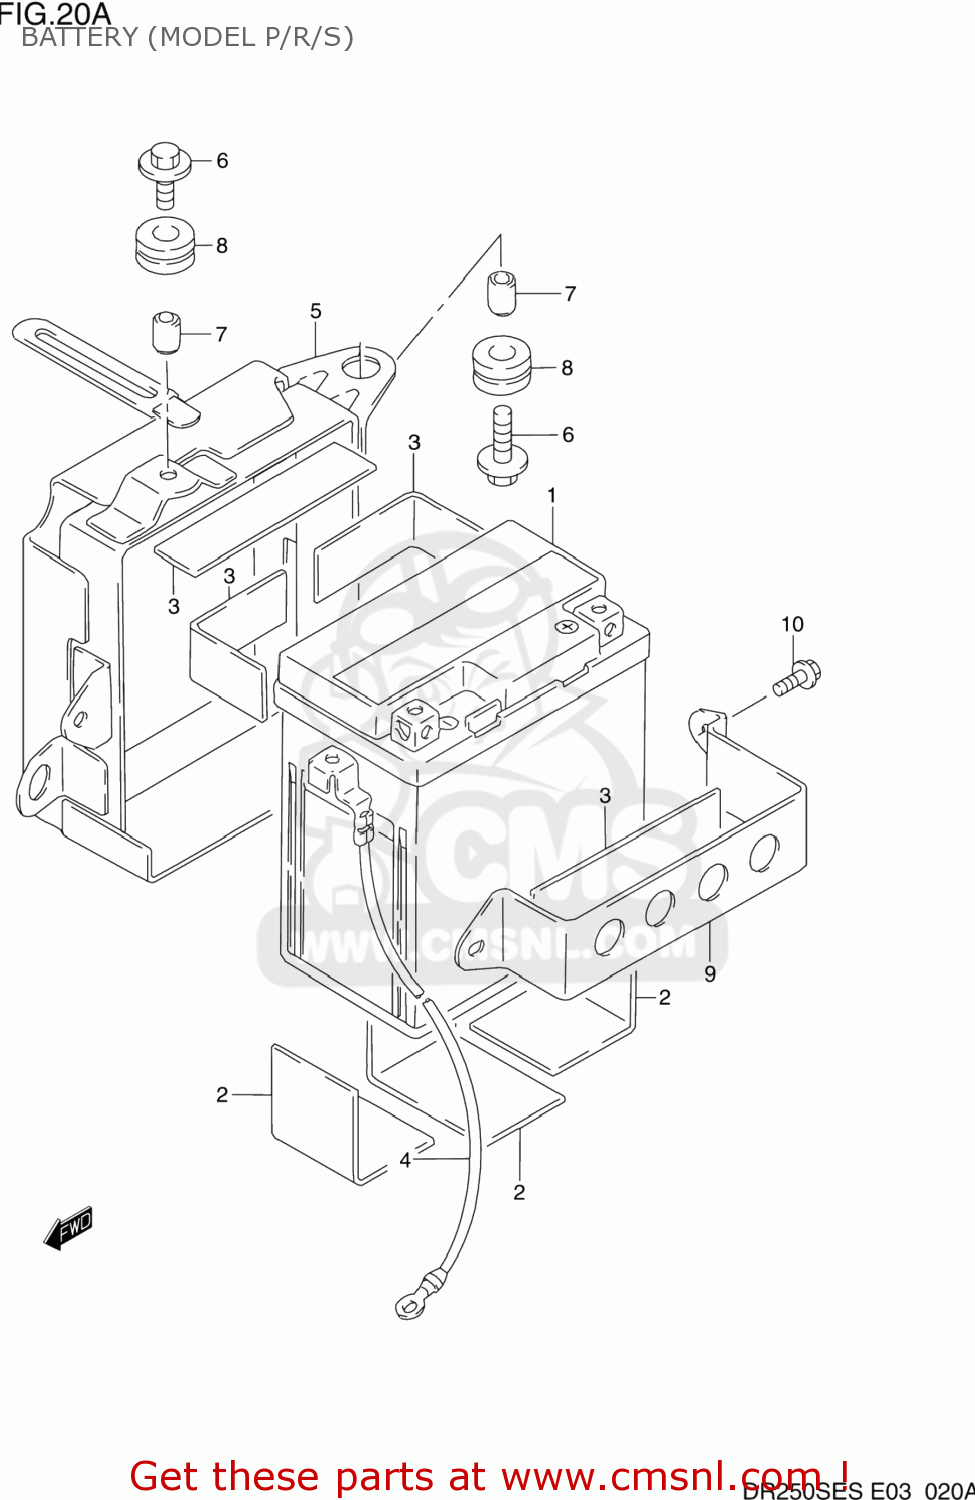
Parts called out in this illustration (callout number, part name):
1	BATTERY ASSEMBLY (12V) YTX
2	PROTECTOR(170X95X3.0)
3	PROTECTOR(170X95X3.0)
4	WIRE,BATTERY MINUS LEAD
5	HOLDER,BATTERY
6	BOLT(6X20)
7	SPACER (6.8X10X9)
8	CUSHION
9	COVER,BATTERY HOLDER
10	SCREW(6X10)
